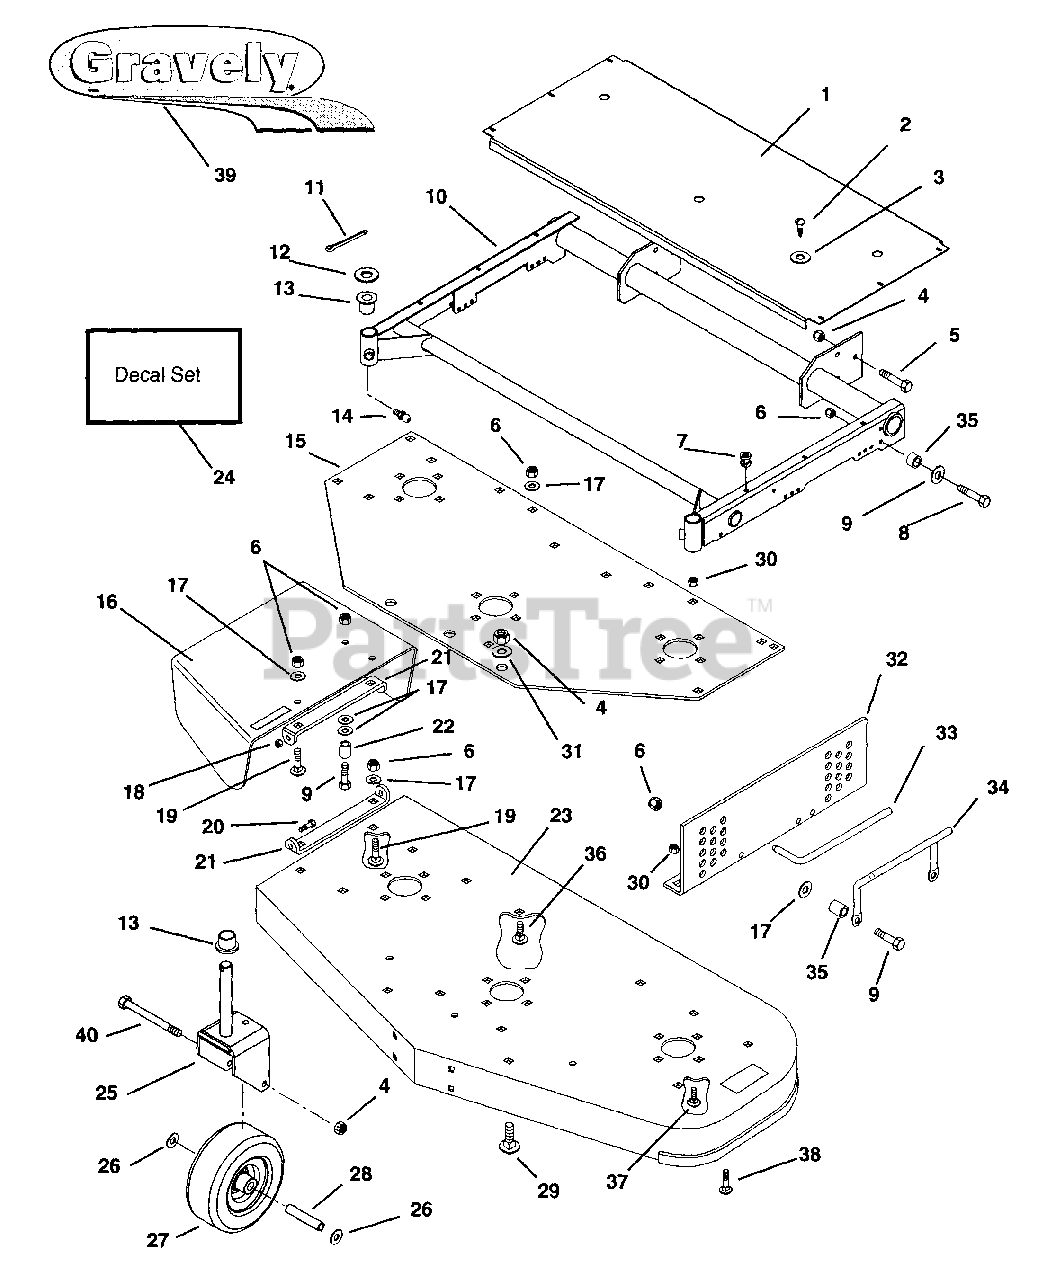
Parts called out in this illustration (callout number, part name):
1	Guard, 50"
2	Screw-Tapping, .25-20 x .50 Hex Slot Head
3	Washer-Flat-Steel .281 x .625 x .065
4	Nut, Locking .50-13
5	Bolt, Hex.50-13 x1.50
6	Nut-Locking-Nylon .375-16 w/Insr Grade 2
7	Grommet, Plastic
8	Bolt-Hex .38-16 x 1.50 Grade 5
9	Washer-Flat-Steel .390 x 1.5 x .125
10	Weldment, Mower Frame
11	Pin, Cotter .187 x 1.50
12	Race, Bearing Thrust
13	Bushing-Flange 1.03 x 1.75 x .750 Nylon
14	Fitting, Lube .25-28
15	Plate, Support
16	Shield, Safety Ext. 50" Mower
17	Washer-Flat-Steel .406 x .812 x .065
18	Nut, Locking .25-20
19	Bolt, Round Head Square Neck .375-16 x 1.00
20	Bolt, Hex .25-20 x .875
21	Bracket, Chute
22	Stop, Chute
23	Weldment, 50" Mower Fabricated
24	Decal, Set
25	Weldment, Caster Fork
26	Washer-Flat-Steel .812 x 1.496 x .134
27	Wheel, Gauge 9 x 3.50
28	Bearing, Gauge Wheel .750 x .532 x 3.97
29	Bolt, Round Head Square Neck .50-13 x 1.00
30	Nut, Locking .312-18 x .625
31	Washer-Flat-Steel 531 x 1.250 x .100
32	Bracket, Mower Side Support Left Hand
32	Bracket, Mower Side Support Right Hand
33	Pin, Mower Locking
34	Handle
35	Bushing
36	Bolt, Carriage .375-16 x .75
37	Bolt, Round Head Square Neck .312-18 x .625
38	Bolt, Carriage .312-18 x 1.00
39	Decal, Gravely Logo
40	Bolt, Hex .5-13 x 5.50
